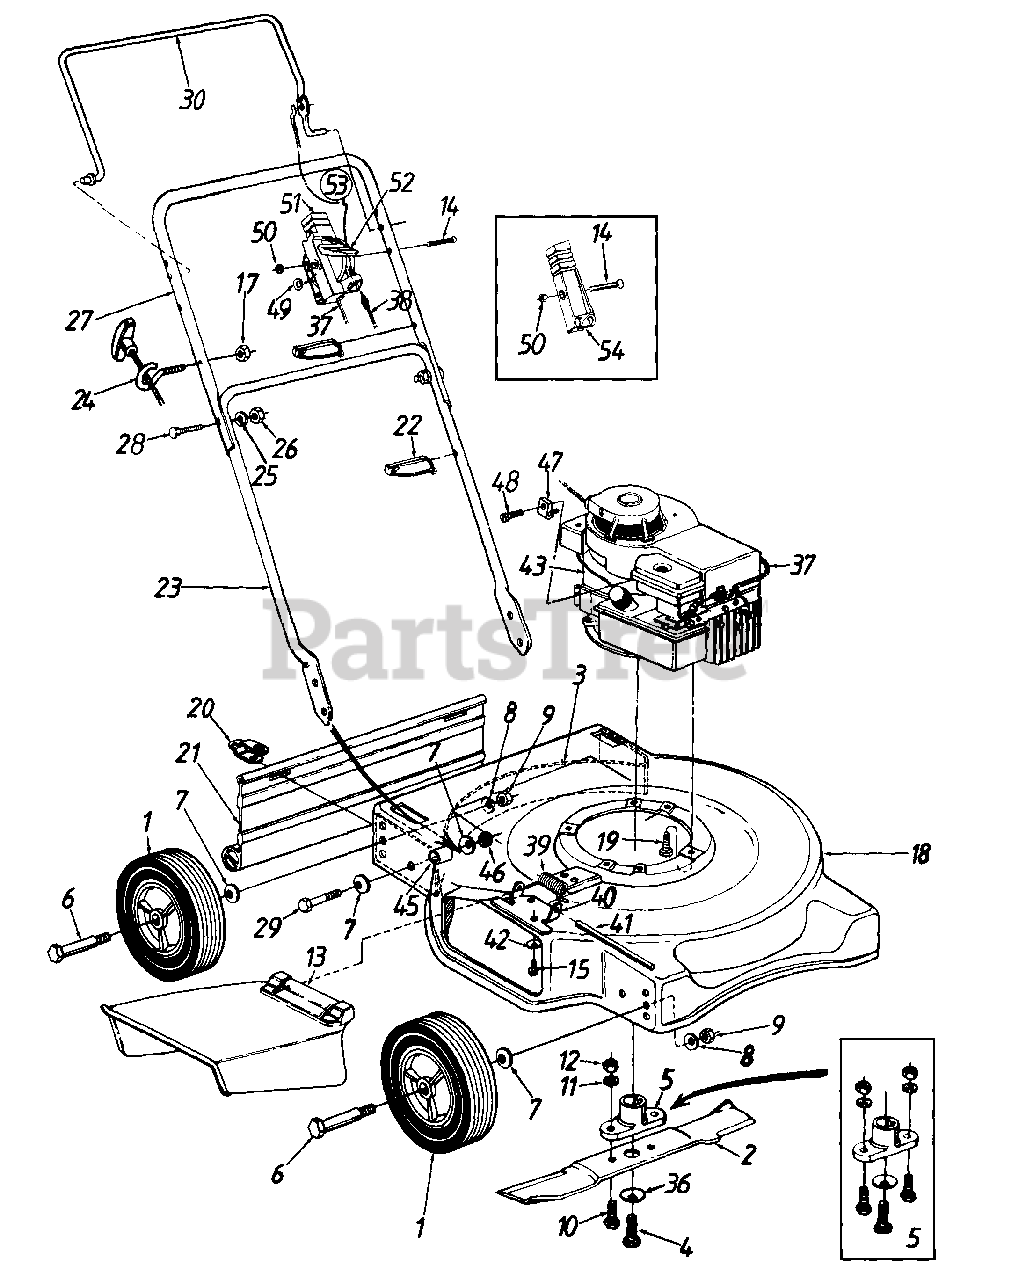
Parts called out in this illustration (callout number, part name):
1	Wheel Ass'y. Complete
2	20" Blade
5	Blade Adapter Kit (Keyed)
6	Axle Bolt
7	Bell-Wash. .380" I.D. x .88"
8	Bell-Wash. .39" I.D. x 1.13"
9	Hex Nut 3/8-16 Thd.
10	Hex Bolt 3/8-24 x 1" Lg.
11	L-Wash. 3/8" I.D.
12	Hex Nut 3/8-24 Thd.
13	Chute Deflector Ass'y.
14	Oval C-Sunk Scr.
15	Self-Tap Scr. 1/4-20 x .5" Lg.
17	Hex L-Nut 1/4-20 Thd.
20	Hinge Clip
21	Rear Flap 16.69" Lg.
22	Cable Tie
24	Rope Guide
25	L-Wash. 5/16" I.D.
26	Hex Nut 5/16-18 Thd.
29	Hex Bolt 3/8-24 x 1.5" Lg.
36	Bell-Wash. .39" I.D.
37	Throttle Control Wire - 51"
38	Control Cable - 36"
39	Torsion Spring
40	Adapter Plate
41	Hinge Pin
42	Bell-Wash. 1/4" I.D.
43	Engine
45	Spacer
46	Hex L-Nut 3/8-24 Thd.
47	Casing Clamp
48	Hex Wash. Hd. Scr. #10-32 x .62" Lg.
49	Spring Wash. .66" I.D.
50	Hex L-Nut 1/4-20 Thd.
51	Throttle Body
52	Throttle Lever
53	Throttle Box Comp.
54	Control Cable Box
